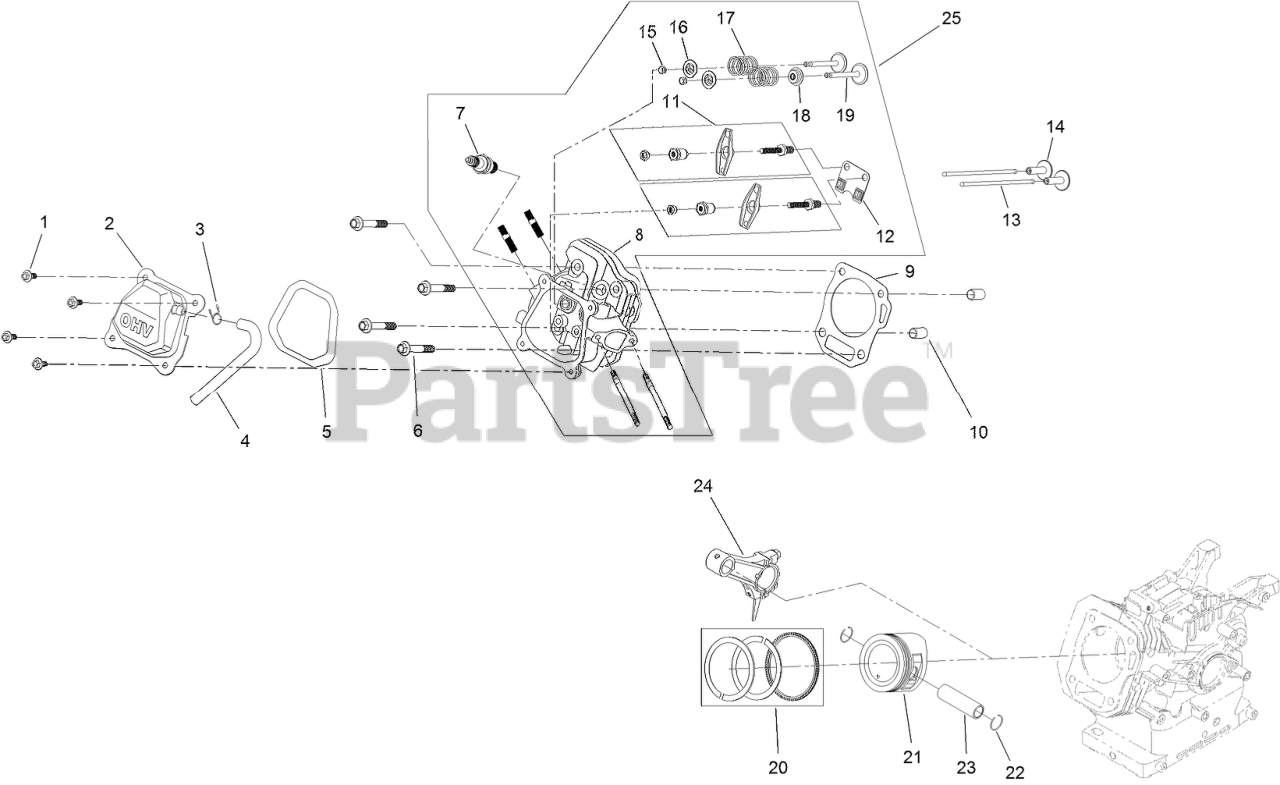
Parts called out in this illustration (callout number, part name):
1	SCREW-HHF
2	COVER-VALVE
3	CLAMP-HOSE
4	TUBE-BREATHER
5	GASKET-COVER, VALVE
6	SCREW-HHF
7	SPARK PLUG
8	HEAD-CYLINDER
9	GASKET-HEAD, CYLINDER
10	PIN-DOWEL
11	ROCKER ARM ASM
12	PLATE-GUIDE, PUSH ROD
13	ROD-PUSH
14	TAPPET-VALVE
15	ROTATOR-VALVE
16	RETAINER-SPRING, VALVE
17	SPRING-VALVE
18	SEAL-STEM, VALVE
19	VALVE SET
20	RING SET, PISTON
21	PISTON
22	CLIP-PIN, PISTON
23	PIN-PISTON
24	CONNECTING ROD ASM
25	COMPLETE HEAD ASM
